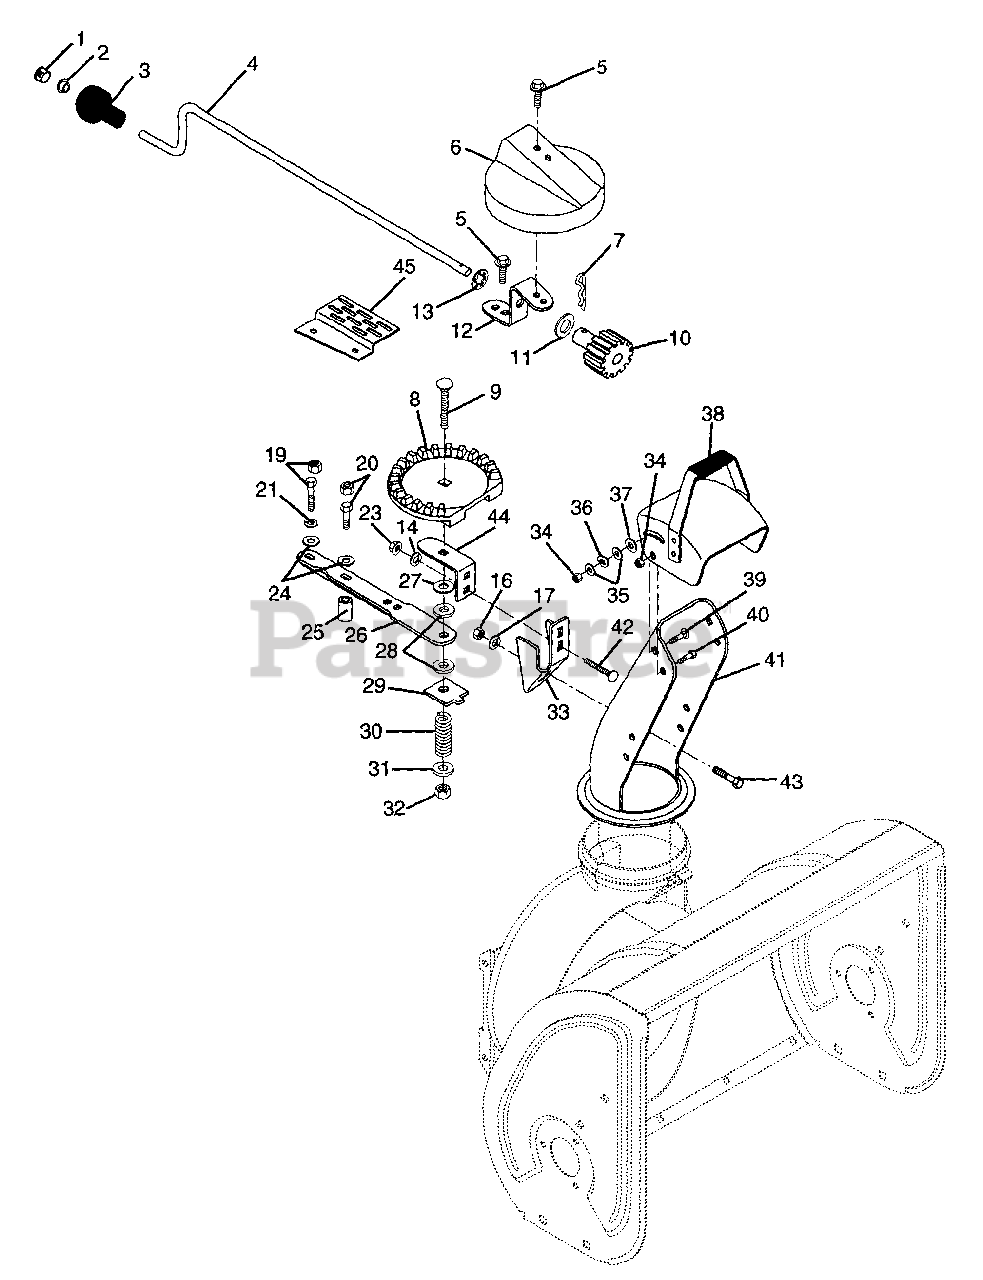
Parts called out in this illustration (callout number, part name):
1	HOLE PLUG
2	RG-RTNG-EXT .375X.010
4	CHUTE CRANK
5	@SCR-TAP .25-20X.50 HWH TR YWZ
6	GEAR COVER
7	PIN-HAIR INT .08X.38X1.42 YWZC
8	CHUTE GEAR
9	@BLT-RDHDSQNK .38-16X2.25 G5YZ
10	PINION-CHUTE
11	WSHR-FL-STL .630X1.005X.062 YZ
12	BRACKET-GEAR
13	PUSHNUT .625
14	@WSHR-LK .25X.062 REG YWZC
16	@NUT-HEX .25-20 YWZC
17	WSHR-LK .250X.077 HVY YWZC
19	@BLT-HEX .31-18X.75 GR5 YWZC
20	@BLT-HEX .25-20X1.50 GR5 YWZC
21	WSHR-LK .312X.097 HVY YWZC
23	@NUT-HEX .25-20 YWZC
24	WSHR-FL-STL .328X.875X.062YWZC
25	SPACER .280X.625X.760
26	BRACE, CHUTE CONTROL
27	WSHR-FL-STL .380X1.50X.062 YWZ
28	FRICTION WASHER
29	FRICTION PLATE
30	SG-COMP .187X.56X1.62
31	@WSHR-FL-STL.406X.812X.065 YWZ
32	@NUT-LK-CTR .38-16 YWZC
33	CHUTE STRAP
34	@NUT-LK-CTR .31-18 YWZC
35	WSHR-FL-STL .323X.625X.062 YWZ
36	WAVE WASHER .390X.655X.110
37	WSHR-PLASTIC .390X.875X.062
38	RAKE, RIGHT-24"(.75ID X 10.88)
39	@BLT-RDHDSQNK .31-18X.75 G5YZ
40	@BLT-HEX .31-18X.50 GR5 YWZC
41	DISCHARGE CHUTE
42	@BLT-RDHDSQNK .25-20X.75 G5YZ
43	@BLT-HEX .25-20X.75 GR5 YWZC
44	GEAR STRAP
45	MUFFLER SHIELD
